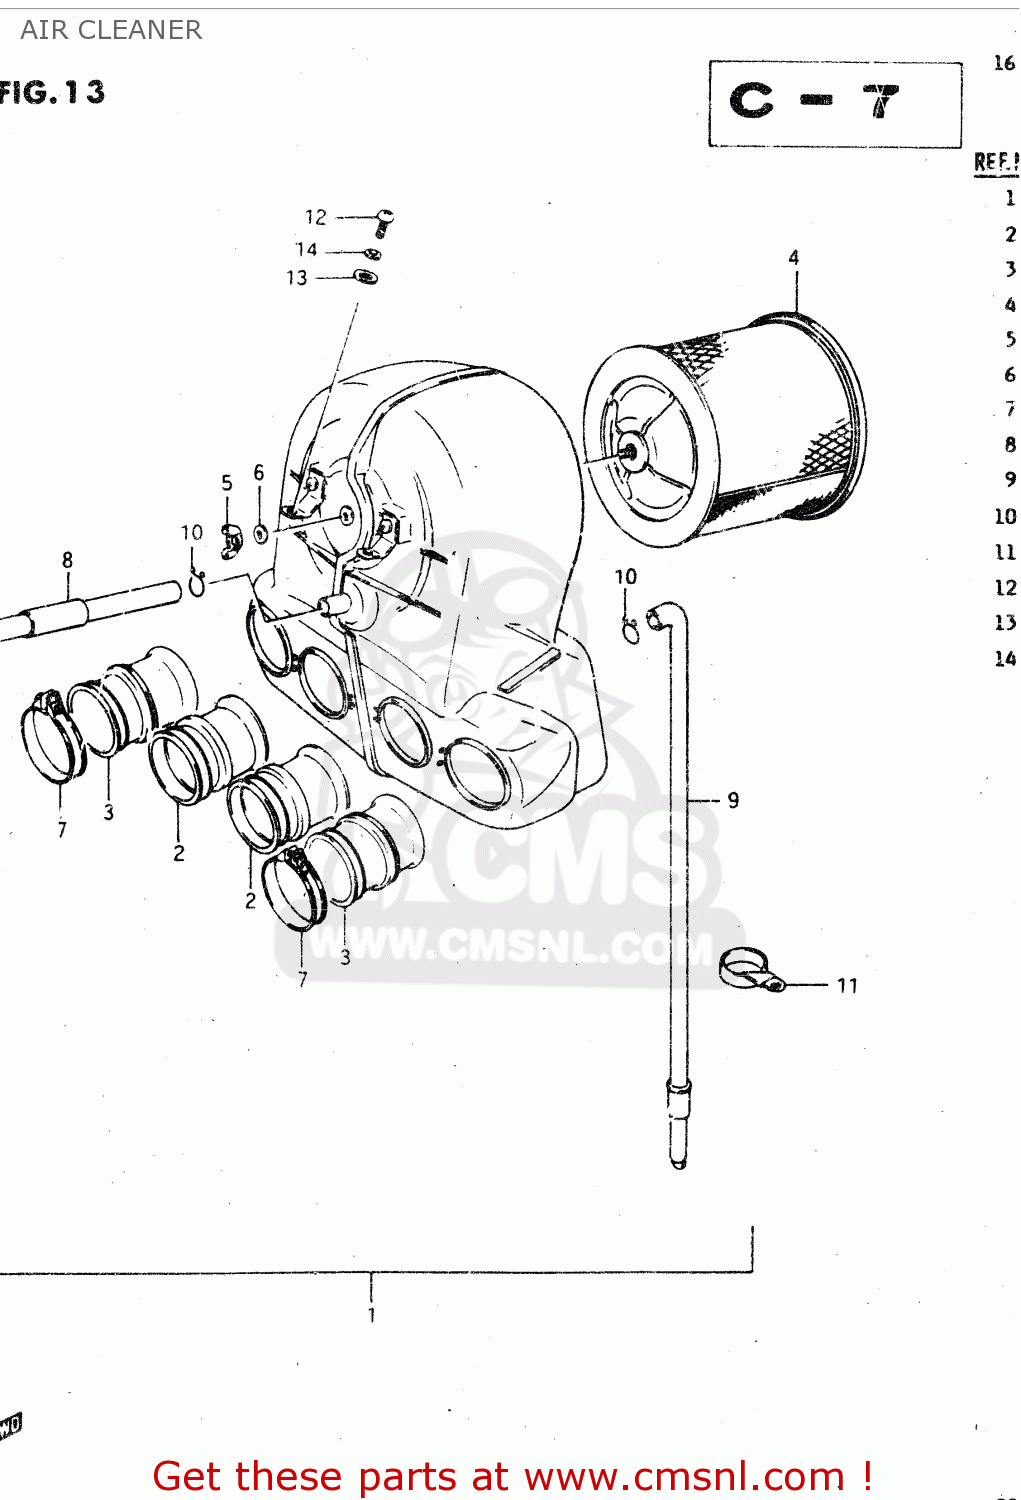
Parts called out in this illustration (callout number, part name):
1	CLEANER ASSEMBLY,AIR
2	TUBE,OUTLET NO.1
3	TUBE,OUTLET NO.2
4	FILTER ASSY
5	NUT, WING
6	WASHER 5MM
7	CLAMP
8	TUBE,BREATHER
9	DRAIN TUBE
10	CLIP
11	CLAMP,AIR CLEANER DRAIN TUBE
12	SCREW
13	WASHER(6.5X16X1.2)
14	WASHER,LOCK
